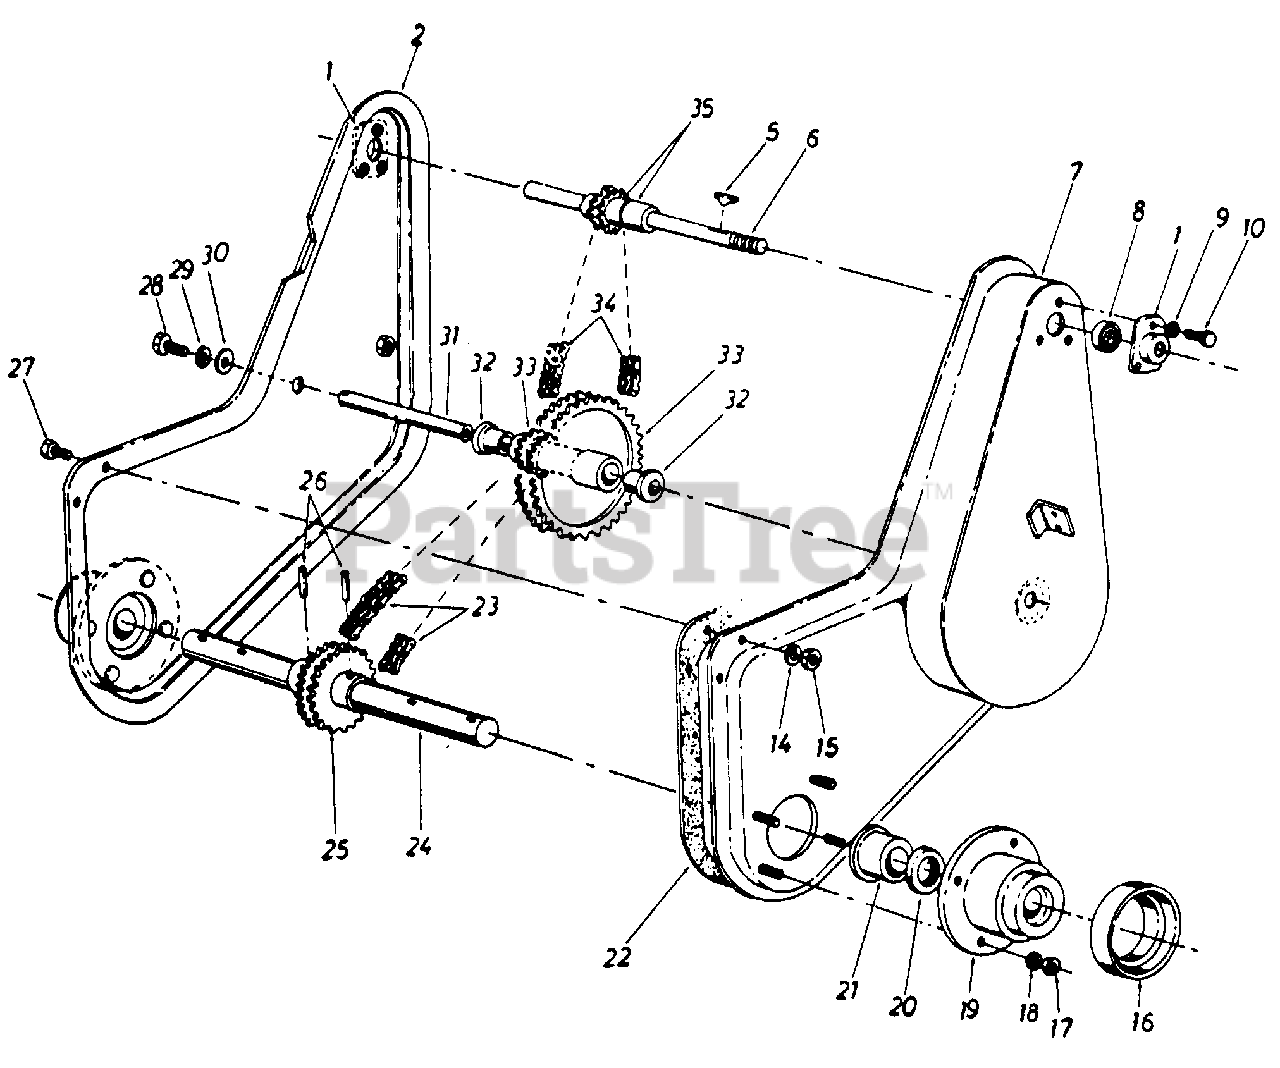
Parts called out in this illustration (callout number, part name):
1	Bearing Housing 1.375" Dia.
2	Housing Assembly R.H.
5	#6 Hi-Pro Key 5/32" x .62" Lg.
6	Input Shatt Assembly
9	L Wash. 1/4" I.D.
10	Hex Bolt 1/-20 x .62" Lg.
14	L Wash. 1/4" I.D.
15	Hex Cent. L-Nut 1/4-20 Thd.
16	Dust Cap Cover
17	Hex Cent. L-Nut 5/16-18 Thd.
18	L-Wash. 5/16" I.D.
19	Cast Bearing Housing
20	Oil Seal
21	Flange Bearing 1.25" I.D. x 1 .75" O.D.
22	Gasket
23	Roller Chain #40-2 x 34.0 0 Lg.
24	Tine Shaft
25	Double Sprocket T24-2 Teeth 1/2" Pitch
26	Spiral Pin 3/8" Dia. x 2.00" Lg.
27	Hex Bolt 1/4-20 x .62" Lg.
28	Hex Bolt 5/16-18 x 75" Lg.
29	L-Wash. 5/16 I.D.
30	Fl-Wash. 5/16 I.D.
31	Sprocket Shaft
32	Flange Bearing .62 I.D. x .75 O.D.
33	Double Sprocket Assembly
34	Roller Chain #35-2 x 36.75" Lg.
35	Spacer 5/8 I.D. x 7/8" O.D.
